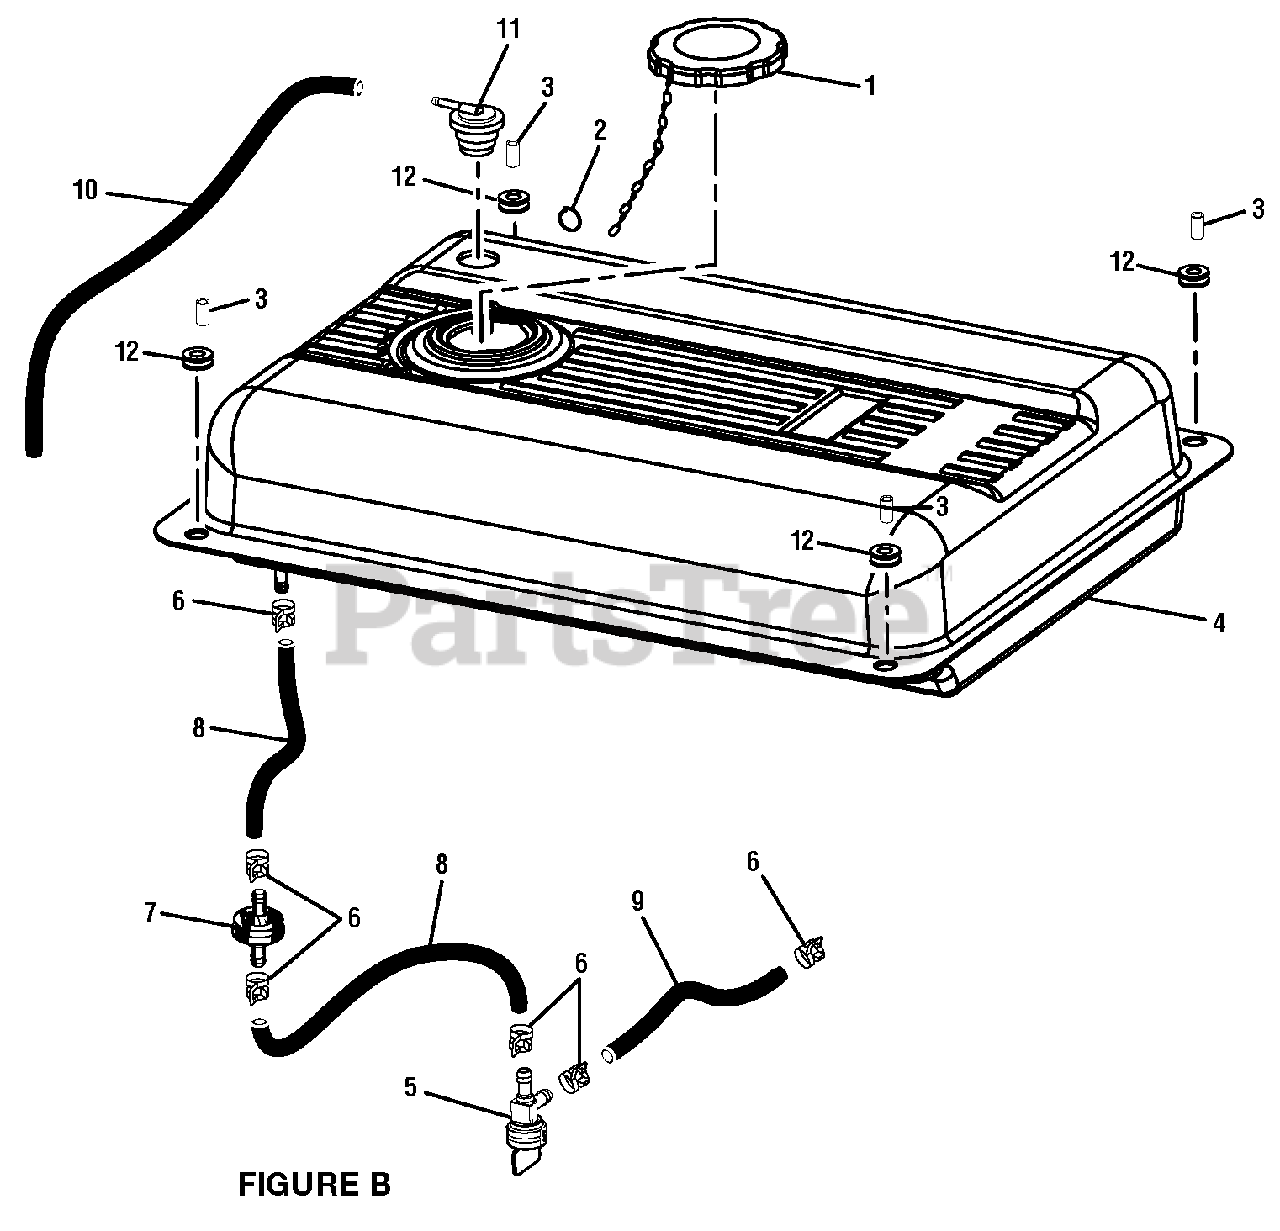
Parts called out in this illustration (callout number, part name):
1	Fuel Tank Cap
2	Ring Clip
4	Fuel Tank Assembly
5	Fuel Valve
6	Fuel Line Clamp (1/2 in.)
7	Fuel Line Filter
8	Fuel Line
9	Fuel Hose (1/4 in.)
10	Vapor Hose
11	Vapor Vent
12	Isolator (12 mm)
